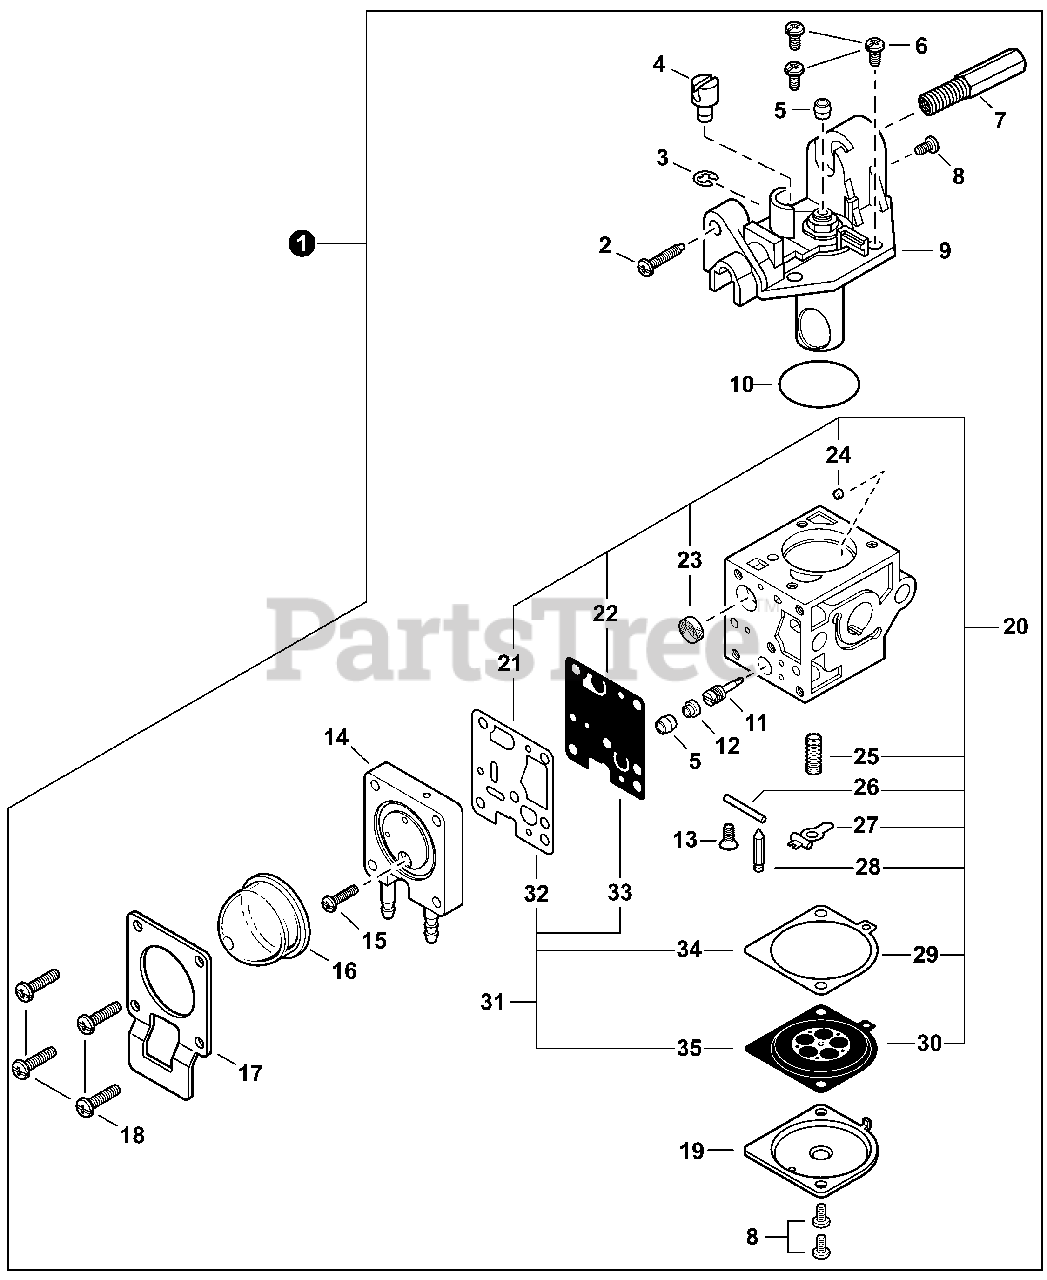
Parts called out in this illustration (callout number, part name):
1	CARBURETOR - RB-K112
2	SCREW, THROTTLE ADJUST
5	CAP, LIMITER
7	ADJUSTER, THROTTLE CABLE
9	COVER ASSY, ROTOR
11	NEEDLE, HIGH SPEED
14	BODY ASSY, PURGE
16	BULB, PURGE
17	RETAINER, PURGE BULB
19	COVER, METERING DIAPHRAGM
20	REPAIR KIT, CARBURETOR
21	GASKET, PUMP
22	DIAPHRAGM, PUMP
23	SCREEN, FUEL INLET
24	GUIDE, ROLLER
25	SPRING, METERING LEVER
26	PIN, METERING LEVER
27	LEVER, METERING
28	VALVE, INLET NEEDLE
29	GASKET, METERING DIAPHRAGM
30	DIAPHRAGM, METERING
31	GASKET / DIAPHRAGM KIT
32	GASKET, PUMP
33	DIAPHRAGM, PUMP
34	GASKET, METERING DIAPHRAGM
35	DIAPHRAGM, METERING
